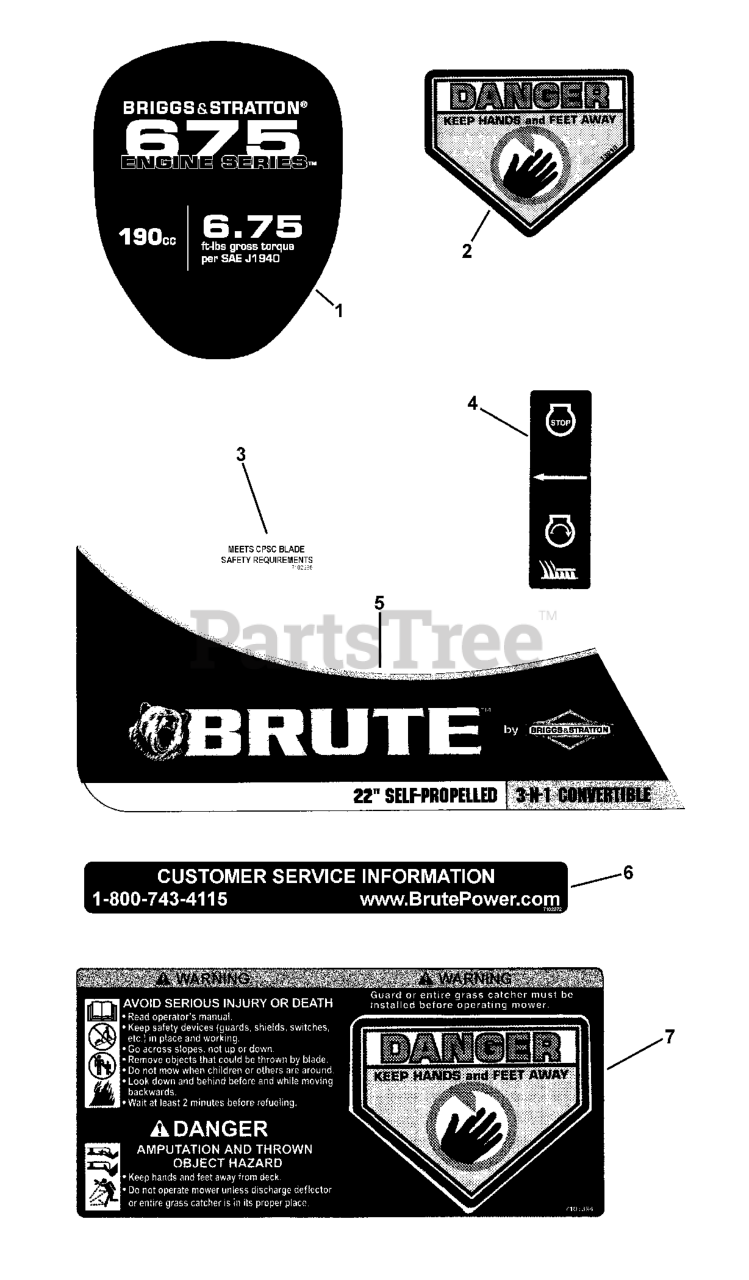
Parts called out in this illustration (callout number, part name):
1	DECAL, Engine, TP, Brute 675
2	DECAL, Danger, Cut Finger
3	DECAL, Blade CPSC
4	DECAL, OPC Bail International Symbol
5	DECAL, Deck Front 22"
6	DECAL, Customer Service, Brute
7	DECAL, Warning, Rear Discharge Door
